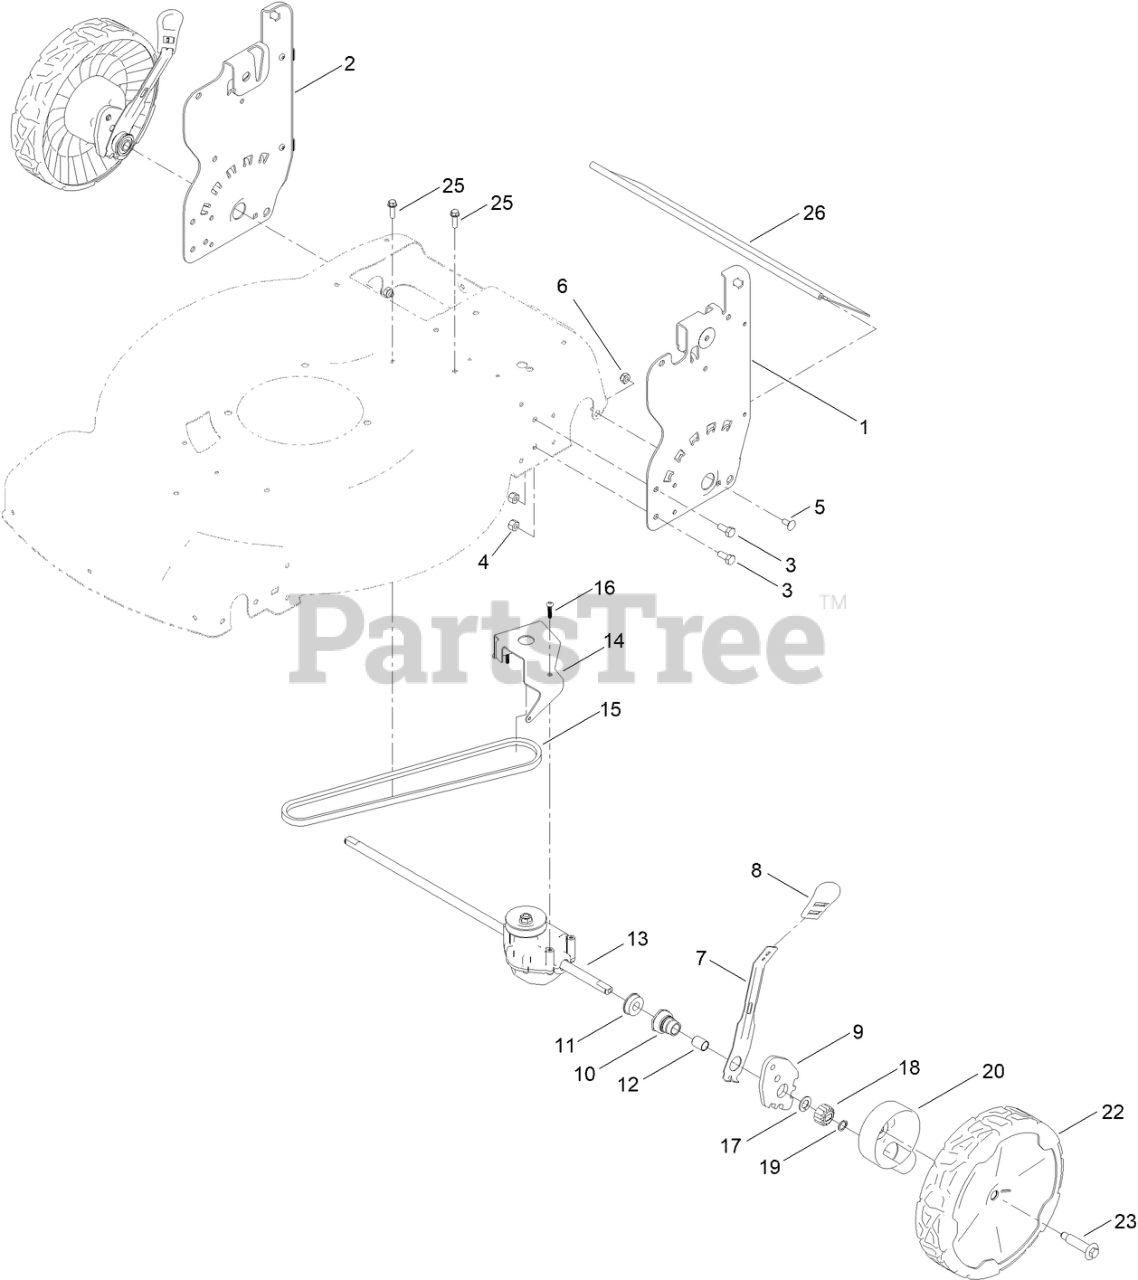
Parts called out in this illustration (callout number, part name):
1	PLATE-HOC, LH (ISO)
2	PLATE-HOC, RH (ISO)
3	SCREW-HH
4	NUT-HEX
5	BOLT-CARR
6	NUT-LOCK
7	ARM-SPRING
8	KNOB-HOC
9	ARM-PIVOT, REAR
10	RETAINER-BUSHING, HOC
11	BEARING-BALL
12	BUSHING-SLEEVE
13	TRANSMISSION-RWD
14	BRACKET-TRANSMISSION
15	V-BELT
16	SCREW-PLASTITE
17	WASHER-THRUST
18	GEAR-PINION, 15T
19	RING-RETAINING
20	ASM-COVER, GEAR (DK GRAY)
22	ASM-9.65" WHEEL, GEARED
23	WHEEL BOLT
25	SCREW-PLASTITE, HWH
26	SHIELD-TRAILING
